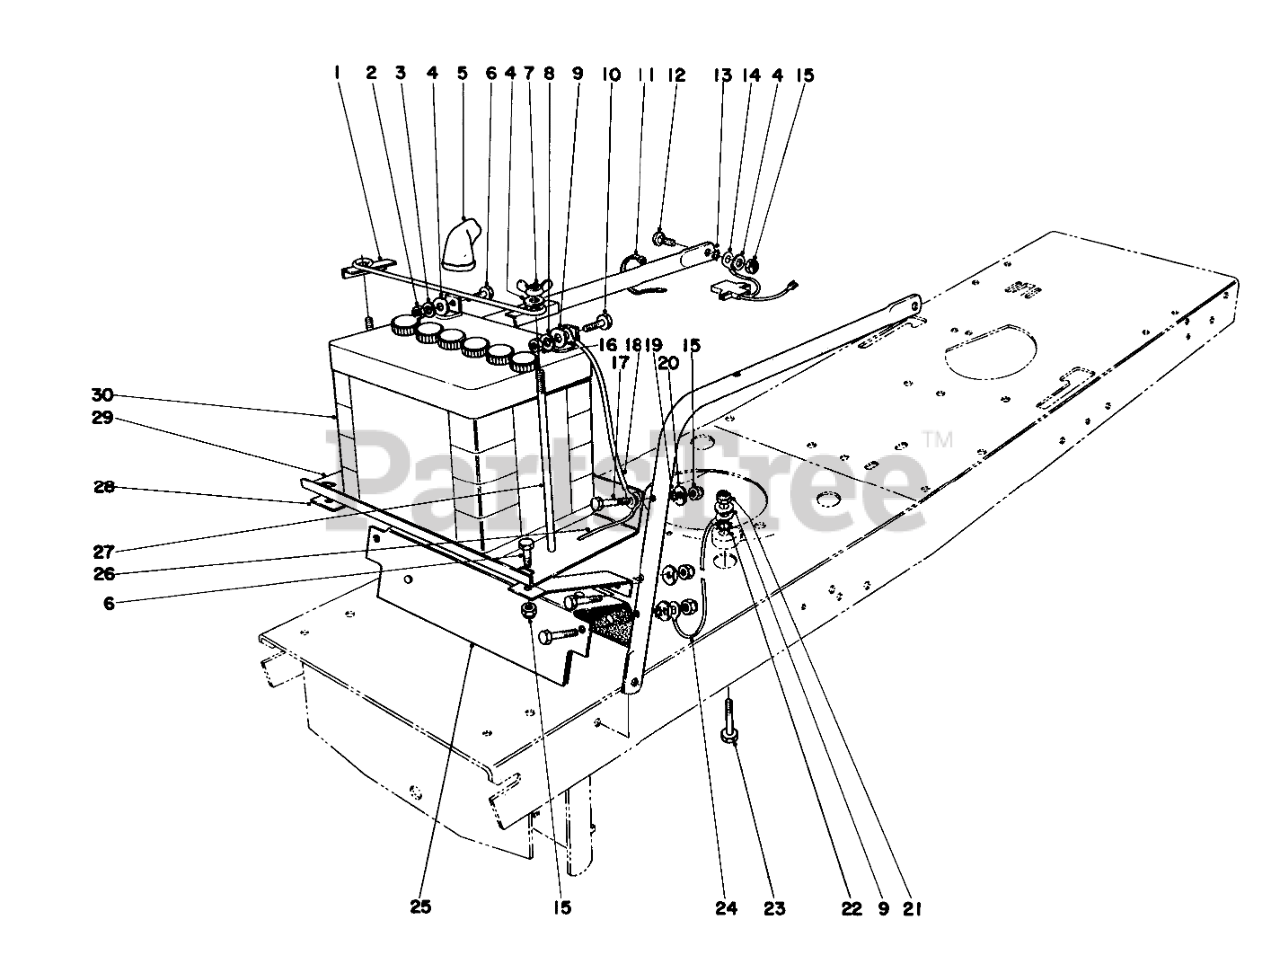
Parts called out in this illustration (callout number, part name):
1	Battery Clamp
2	NUT-HEX
3	WASHER-LOCK
4	WASHER-FLAT
5	BATTERY BOOT
6	SCREW-HH
7	WING NUT
8	WASHER-LOCK
9	WASHER-PLAIN
10	SCREW-HH
11	Cable Tie
12	BOLT-CARR
13	WASHER-LOCK/EXT
14	Wire Assembly
15	NUT-LOCK, CONE
16	NUT-HEX
17	SCREW-HH
18	Wire Assembly Battery to Ground
19	WASHER-LOCK/EXT
20	WASHER
21	NUT-LOCK, CONE
22	WASHER-LOCK
23	SCREW-HH
24	Wire Assembly Engine to Ground
25	Heat Shield
26	Wire Assembly Headlight to Ground
27	BATTERY BOLT
28	Brace Battery Shelf
29	Battery Shelf
30	Battery
